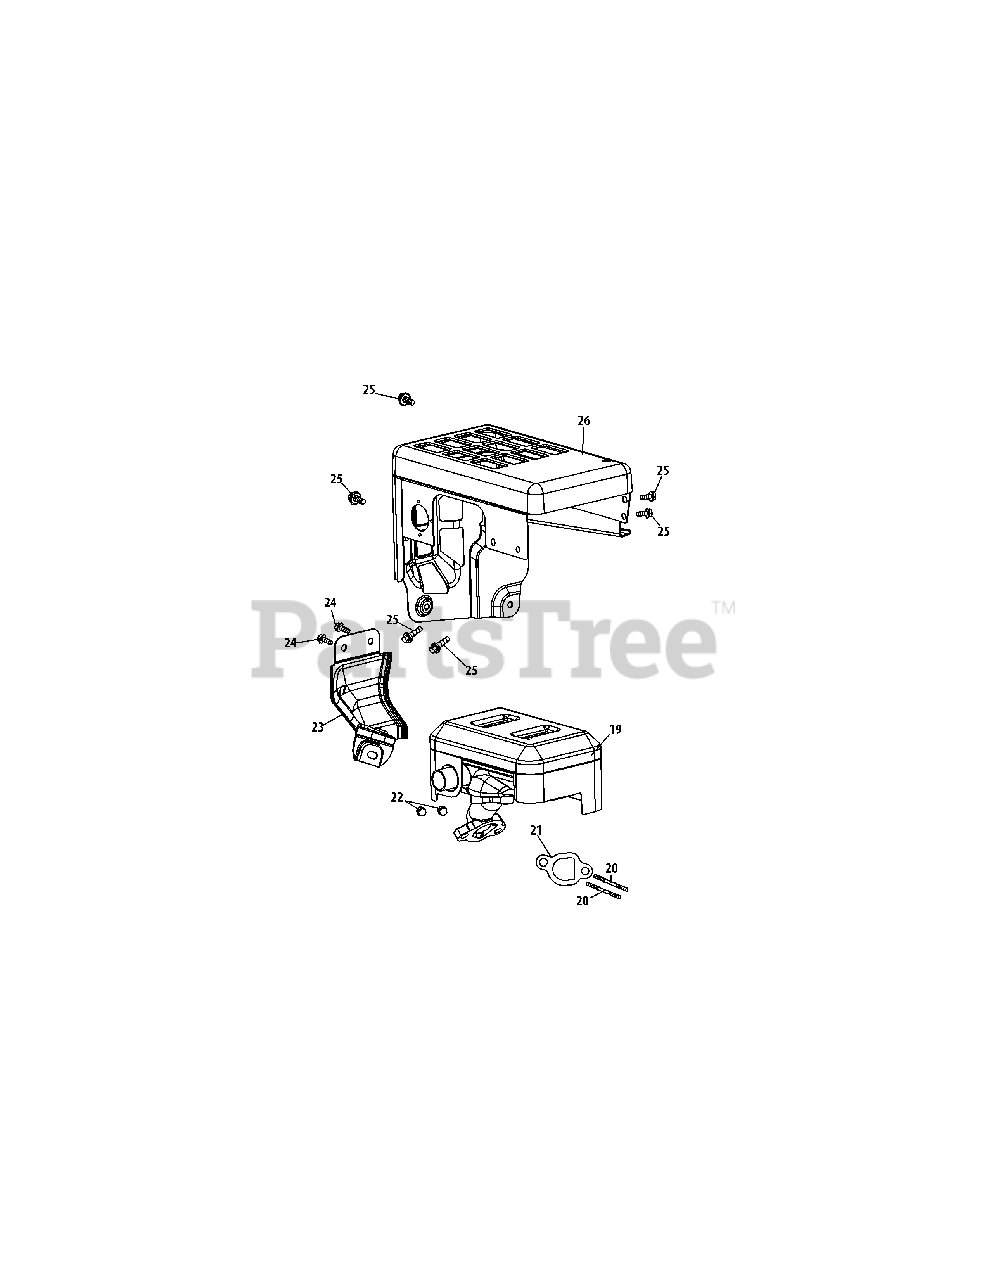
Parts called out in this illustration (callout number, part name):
19	Muffler Assembly
20	Muffler Stud M8×36
20	Muffler Stud Assembly
21	Exhaust Pipe Gasket
23	Exhaust Pipe Shield
24	Bolt M6×10
25	Bolt M6×12
26	Muffler Shield
